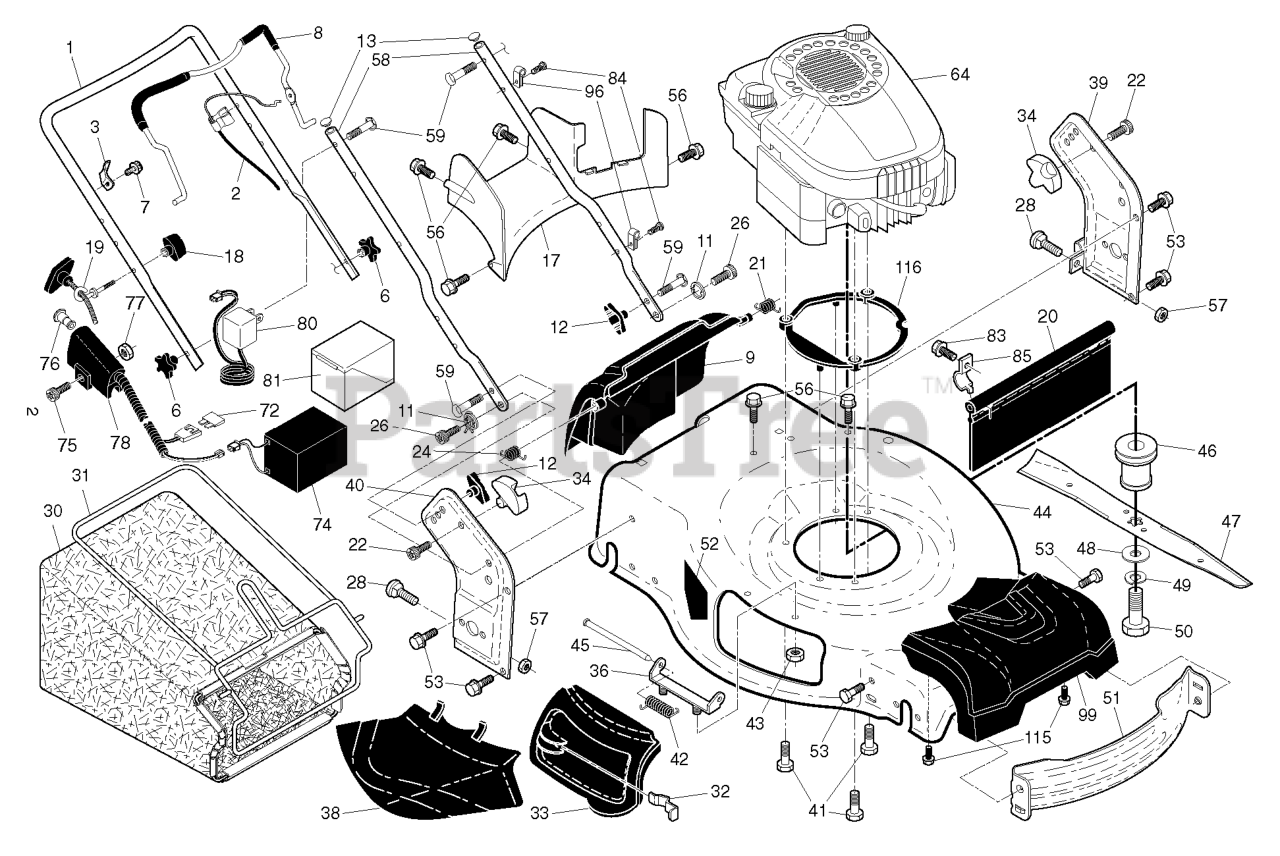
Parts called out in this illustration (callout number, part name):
1	HANDLE.UP.3POS.BS.AW2.GREY
2	CABLE.MZR.50.SNAP-IN
3	BRACKET.UPSTOP.RT
6	KNOB.HANDLE.PLASTIC.STAR.BLACK
8	BAIL.OVER.MOLD.ERGO.MZR.ORANGE
9	DOOR.REAR.ASM.22+.HUSQ.FG/RGD
11	E-RING.12MM.SHAFT
12	KNOB, DEFLECTOR
13	PLUG.PLASTIC.7/8".14-20.GAUGE
17	BAFFLE.REAR.22+RGD.AWD.PLASTIC
18	T-KNOB.NEW ROPE GUIDE
19	GUIDE.ROPE.BLK.ZINC.CHROM
20	SKIRT.REAR.22PLUS.RGD.LW(2 2MC
21	SPRING.LH.BLACK
22	SCREW.PAN.HEAD.#10
24	SPRING.RH.GRAY
26	SCREW,DOOR/HANDLE.PIVOT
28	BOLT.CARRIAGE.LN.5/16-18X.5/8
30	GBAG.B561029EM.GRY/SILV
31	FRAME.GBAG.22+.BLK
32	LATCH.DOOR.ZINC
33	DOOR.MULCH.22 PLUS.HUSQ.GREY
34	BRACKET.GRASSBAG.ATTACHING.BLK
36	BRACKET.ASM.HINGE.21.FWGD.
38	DEFLECTOR.CLIPPING.22.BLACK
39	BRACKET.ASM.HANDLE.LT.22+.GREY
40	BRACKET.ASM.HANDLE.RT.22+.GREY
42	SPRING.TORSION
43	NUT.FLANGE.1-4-20-SERR
44	KIT.HSG.22+AWD.MC.WO.668.TRI
45	ROD.HINGE.21
46	ADAPTER.BLADE.25M.B&S.AWD
47	BLADE.22+4N1.2PIN.5STAR.(P07)
48	WASHER,HARDEN
49	LOCKWASHER
50	BOLT.BLADE
51	BAFFLE.FRONT.22.PLUS
52	DANGER DECAL
53	BOLT.5/16HEX.WHS.HD
56	SCREW.HX.13X.750
57	NUT.FLANGE.5/16
58	HANDLE.LOWER.22+.BT.GRAY
59	BOLT, HANDLE 5/16-18X1.75
74	BATTERY.12V.22+RWGD
75	BOLT.M6-1X40.T30
76	BUTTON.KEY.CYLINDER.BLACK
77	NUT.M6-1 NYLOC
78	HARNESS.ASM.22+RGD.PB.
80	CHARGER.BATT.12V LEAD-ACID.DOM
81	COVER.BATTERY.BOX 22+RDG.GRY
83	TAPPING SCREW
84	FASTENER.PUSH.O.250X0.783
85	BRACKET.SKIRT.22+.BZP
96	CLIP.CABLE.BLK
99	COVER.ASSEMBLY.FRONT.22+AWD
115	SCREW.SHOULDER.5/16X1.375
116	SPACER.AWD.B&S
